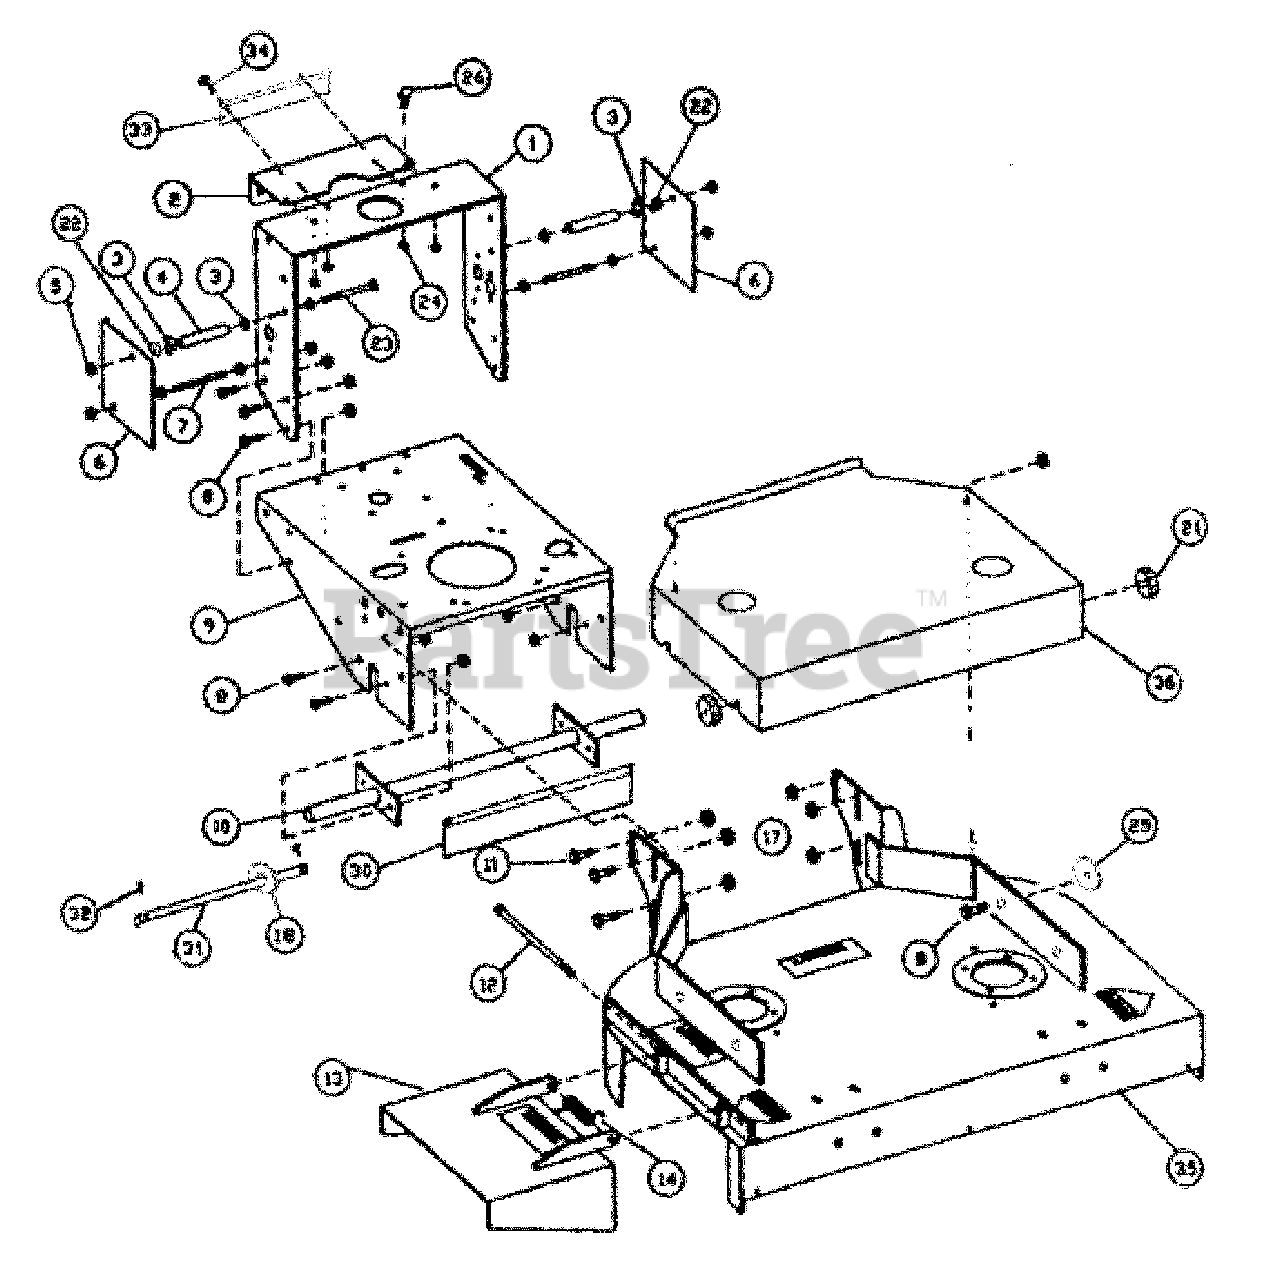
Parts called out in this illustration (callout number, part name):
2	100-002 SHIFT CONSOLE
3	100-003 WASHER
4	100-004 PIVOT TUBE
5	NUT, 200-001 M10
6	100-005 FENDER
7	BOLT, END 200-002 DBL.
8	M10X1.5X25MM HHB GR8.8
11	HHB 200-004 M12 25
12	200-005 HHB M10`240
13	100-007 CHUTE DEFLECTOR
14	100-008 TORSION SPRING
15	200-006 NYLON NUT M10
17	200-007 NYLON NUT M12
18	5/16STD FLAT WASHER.
21	100-009 SAUCER NUT
22	200-006 NYLON NUT M10
23	200-008 HEX.BOLT M10`110
24	200-009 NYLON NUT M6
25	WASHER, 3/8 STD FLAT
26	200-011 BOLT M6`16
30	100-011 SAFETY FLAP
32	200-014 COTTER PIN 2`20
33	100-116 SHIFT PLATE
34	200-063 RIVET 2`5
35	136-001BLUE DECK 36`
36	136-002BLUE HOOD 36`
